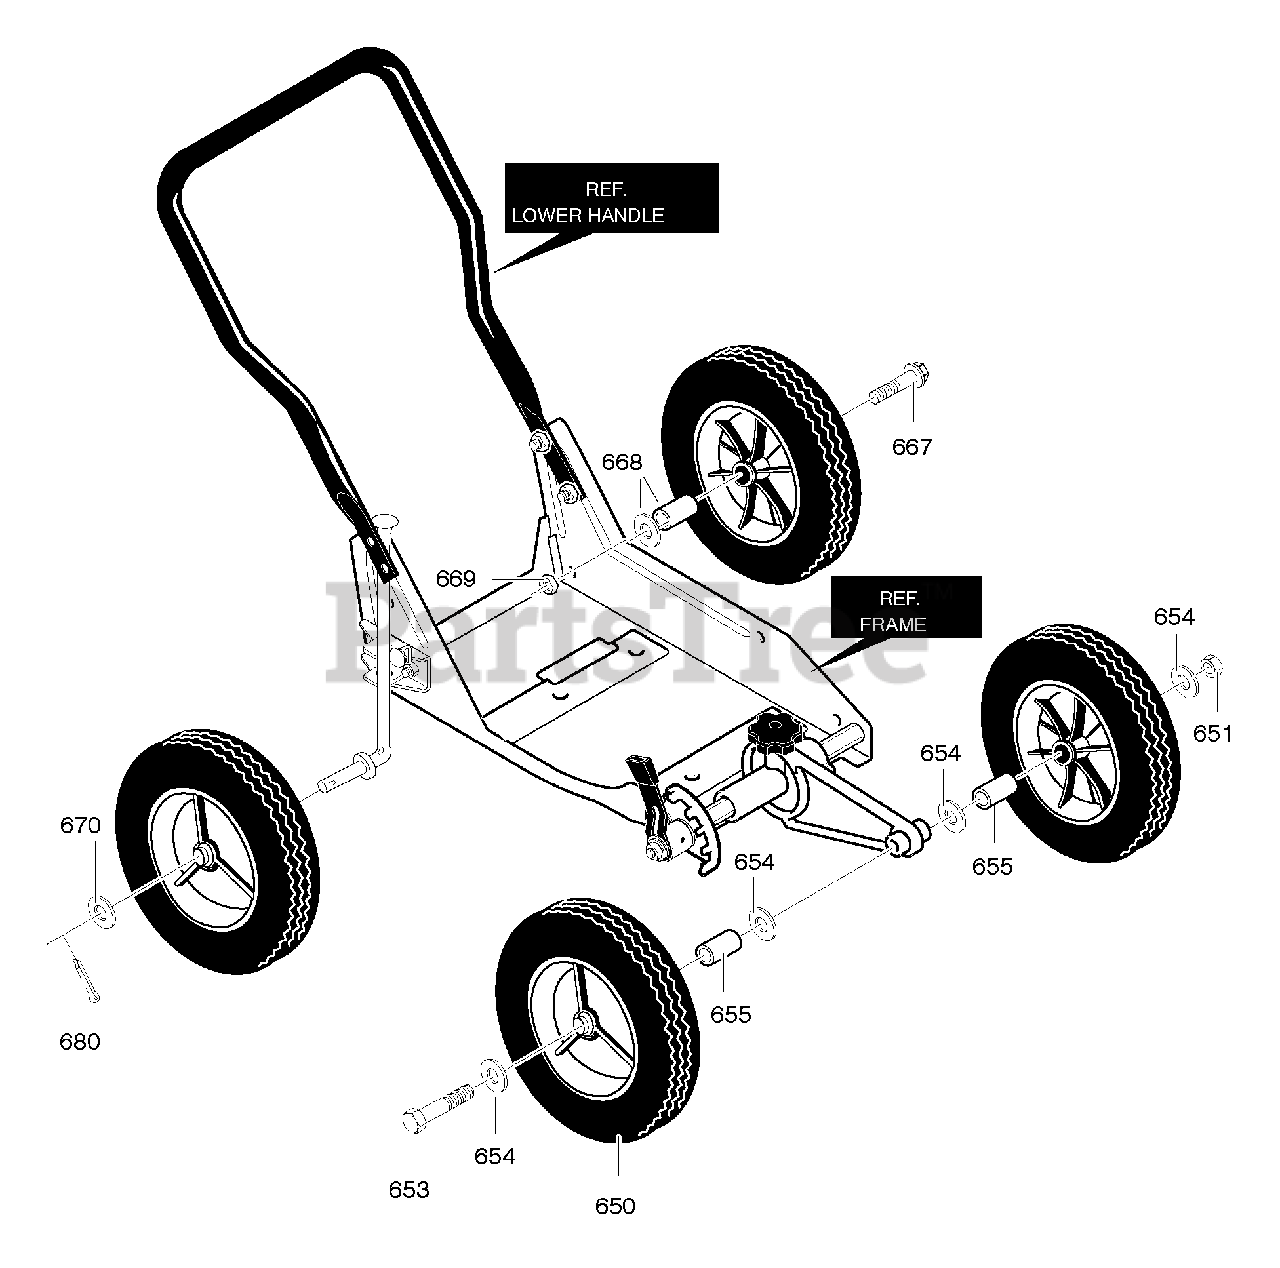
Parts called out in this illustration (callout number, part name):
650	Tire & Rim
651	Nut, 5/16-18
653	Screw, 5/16-18x4.50
654	Flatwasher
655	Spacer, Sleeve
667	Bolt, SHH 3/8-16
668	Spacer & Washer
669	Nut, 3/8-16
670	Flatwasher
680	Cotter Pin
